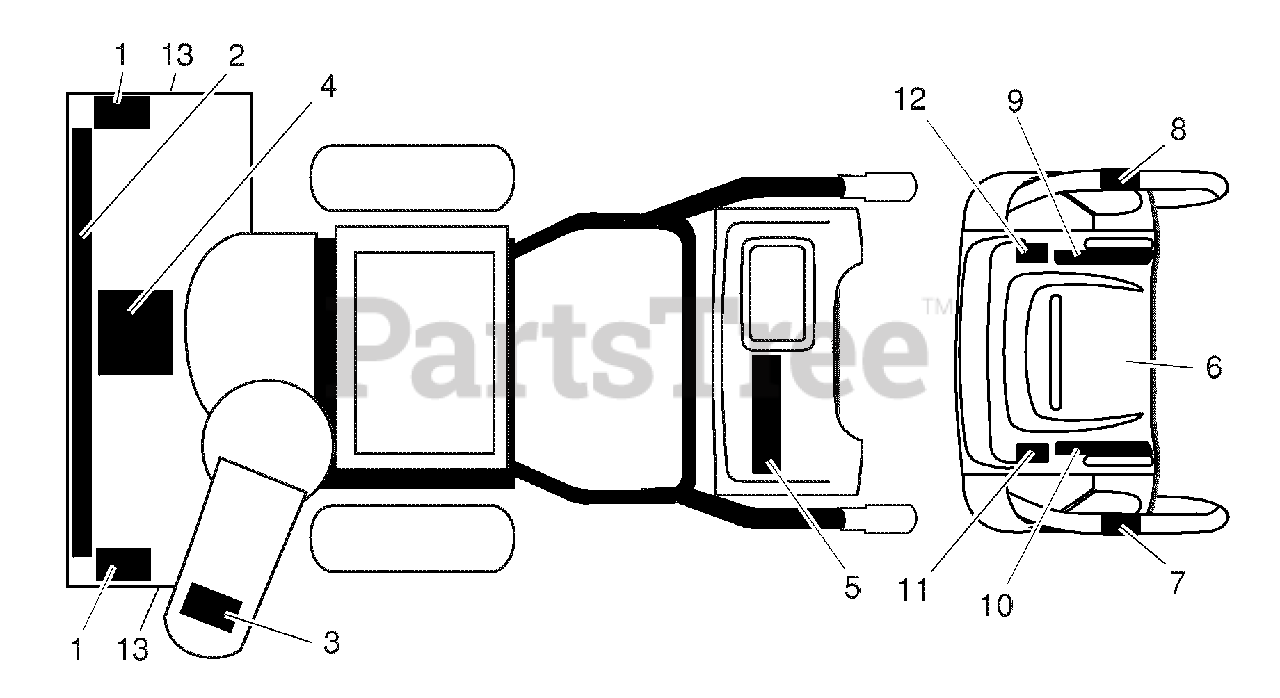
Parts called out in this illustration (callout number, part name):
1	Decal, Danger
2	Decal, Husqvarna
3	Decal, Danger, Deflector
4	Decal, Danger
5	Decal, Husqvarna, 10527SBE
6	Decal, Instruction
7	Decal, Traction Lever
8	Decal, Auger Lever
9	Decal, Speed Control
10	Decal, Remote Deflector
11	Decal, LH Trigger
12	Decal, RH Trigger
13	Decal, Husqvarna, Crown
